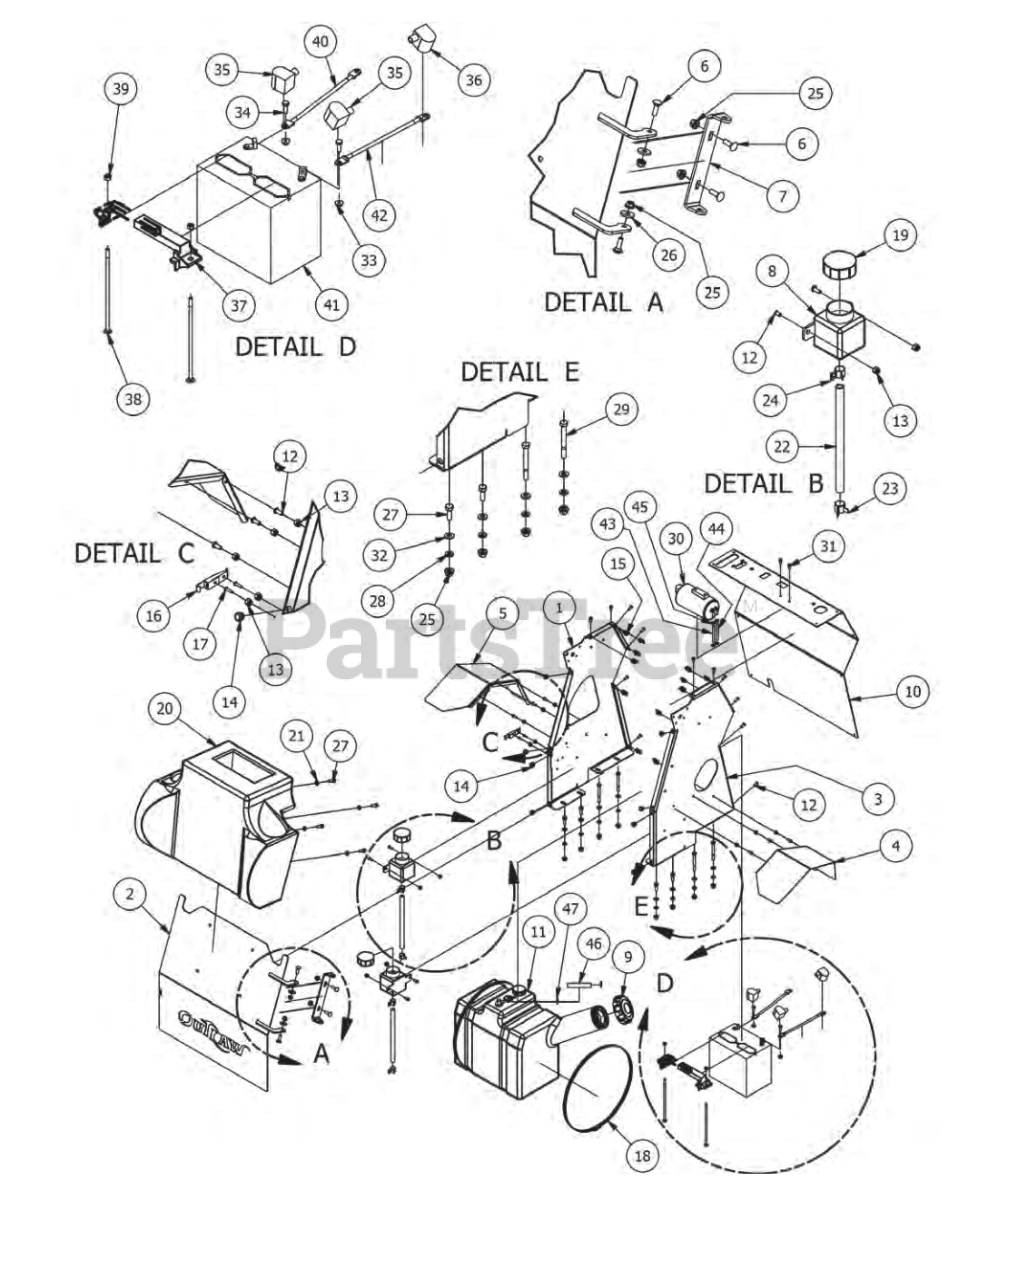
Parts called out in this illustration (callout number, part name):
1	2015 Podium Panel Left
2	Door Panel Assembly
3	2015 Podium Panel Right
4	Fender (Right Side)
5	Fender (Left Side)
6	5/16" x 1" Carriage Bolt
7	Back Cover Hinge Bracket
8	350ml Expansion Tank-CZT
10	2015 Podium Front Panel
12	1/4" x 5/8" BS C/S 18-8 SS
13	1/4" Nylock Nut
14	5/8 Round Insert
15	1/4-20 Cage Nut
16	Steel Pump Cover Latch
17	10-24 X 5/8 BS C/S 18-8 SS
18	Fuel Tank Clamp-Stand On
19	Hydraulic Tank Cap
20	Cushion-2015 Stand On Mower
21	1/4" Flat Washer
22	3/8 clear hose
23	1/2 Hose Clamp
24	3/8 hose clamp
25	5/16" Flange Nut Zinc W/Serrations
26	360 ID Plastic Washer
27	5/16" x 1" Bolt
28	5/16" Lock Washer
29	5/16" x 3" Hex Bolt
30	Carbon Canister ZT,CZT,Outlaw
31	M6-1.0 X 16MM Hex Bolt
32	5/16" Flat Washer
33	1/4-20 Hex Flange Nuts Zinc w/Serrations
34	1/4-20 x 3/4 GR 5 Hex Bolts Zinc
35	Black Boot For ground cable
37	Battery Hold Down
38	1/4-20 X 8 Carriage Bolt
39	1/4-20 Hex Nut
40	Ground Cable
42	24 in red battery cable
43	1/4" vinyl tubing
44	3/16 vinyl tubing
45	3/16 vinyl clamp
46	1/4 Fuel Line
47	1/4 fuel clamp
